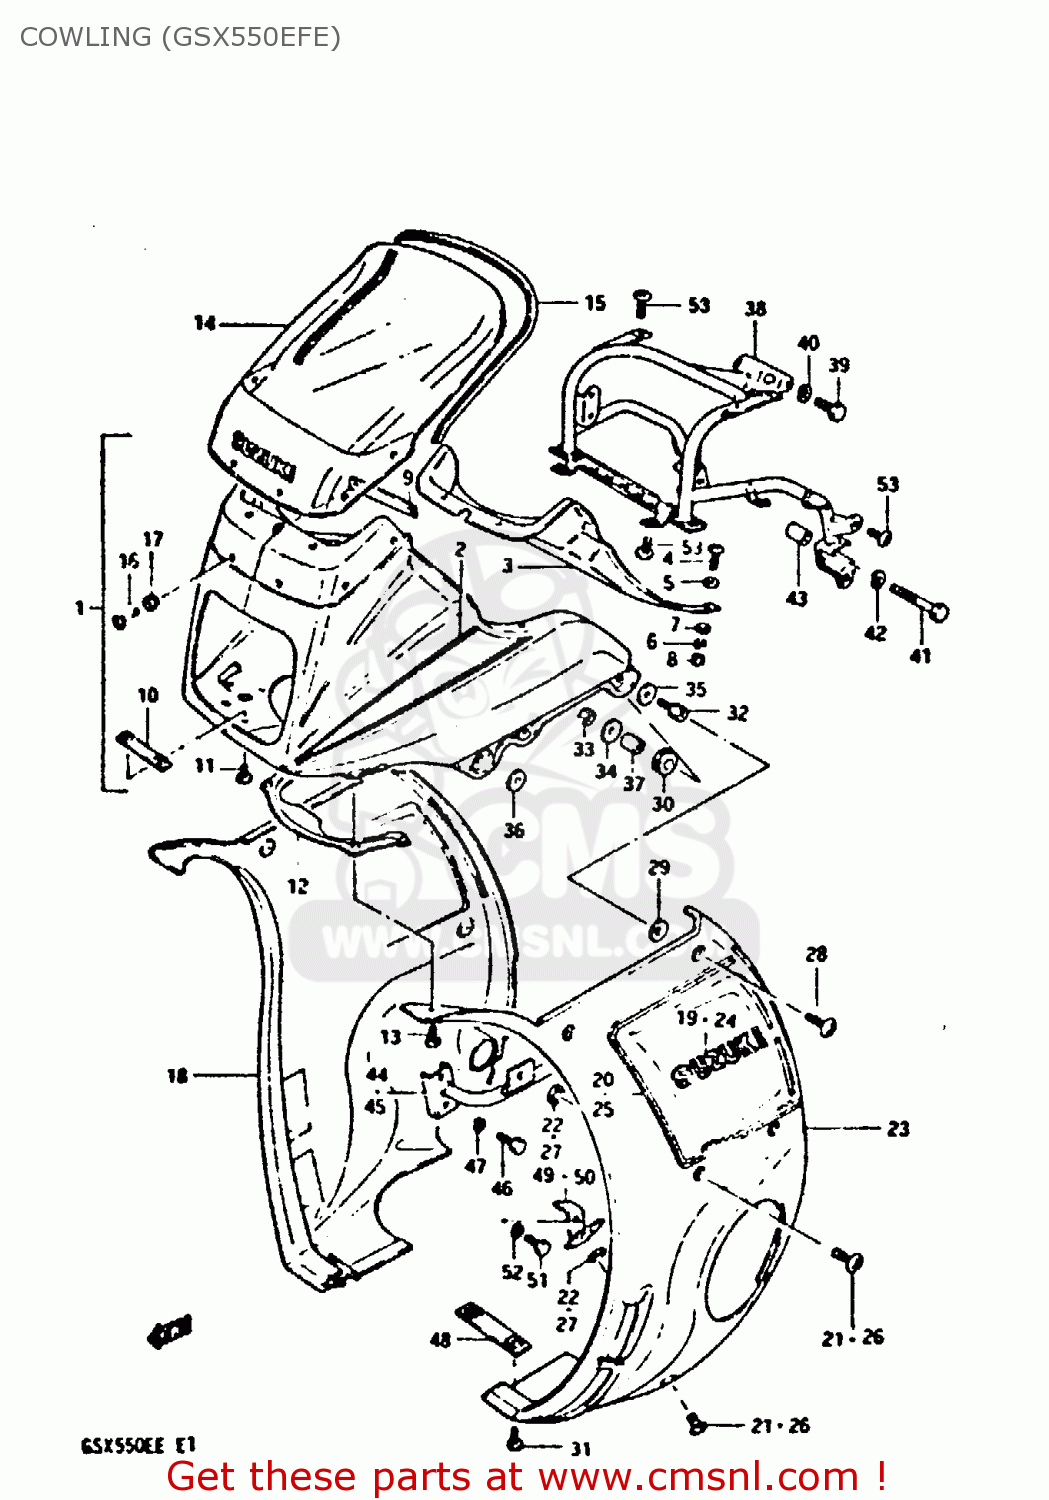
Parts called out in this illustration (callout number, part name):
1	COWLING ASSY (BLUE)
2	TAPE SET
3	PANEL,COWLING,UPPER
4	SCREW
5	WASHER,5MM
6	WASHER,LOCK
7	WASHER,5MM
8	NUT ,5MM
9	BRACKET,COWLING,UPPER
10	BRACKET,COWLING,LOWER
11	SCREW
12	COVER,COWLING,LOWER
13	SCREW
14	WINDOW
15	MOLDING,LOWER
16	SCREW
17	CUSHION
18	COVER,COWLING,RIGHT
19	EMBLEM
20	TAPE SET
21	FASTENER,COWL SIDE COVER
22	E-RING
23	COVER,COWLING,LEFT
24	EMBLEM
25	TAPE SET
26	FASTENER,COWL SIDE COVER
27	E-RING
28	SCREW,COWLING SIDE COVER
29	NUT
30	CUSHION
31	SCREW 6X12
32	BOSS,COWLING BODY,SIDE
33	NUT
34	WASHER (6.5X24X1.6)
35	WASHER, QUTER, REAR
36	WASHER(6.5X18X1)
37	SPACER (6.3X9.1X6.7)
38	BRACE,COWLING
39	BOLT
40	LOCK WASHER
41	BOLT
42	LOCK WASHER
43	SPACER (8.2X12.5X23.5)
44	BRACE,COWLING SIDE,RIGHT
45	BRACE,COWLING SIDE,LEFT
46	BOLT
47	LOCK WASHER
48	BRACE,COWLING,LOWER,FRONT
49	BRACKET,COWLING SIDE,RIGHT
50	BRACKET,COWLING SIDE,LEFT
51	BOLT
52	LOCK WASHER
53	SCREW 6X12
